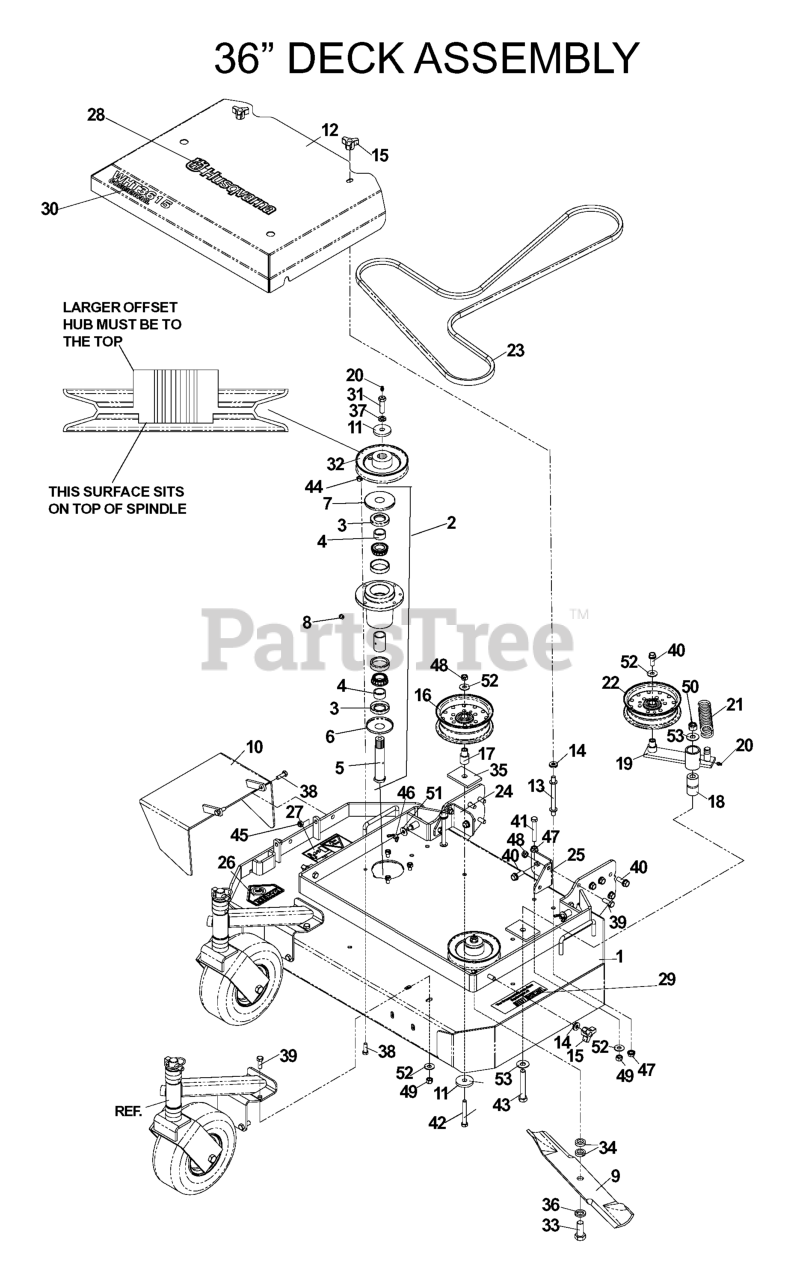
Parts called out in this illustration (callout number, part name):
1	DECK W/DECALS 36"WSL
2	SPINDLE ASM KIT, WHT/KIKW
3	SHAFT SEAL
5	52/61 SPINDLE - SPLINED SHAFT
6	BOTTOM DUST CAP
7	TOP DUST CAP
8	PLUG-VENTED
9	BLADE OEM 18"
10	DEFLECTOR CHUTE
11	SPINDLE WASHER
12	BELT SHIELD, 36" ORANGE
13	SHIELD SPACER
14	WASHER, 3/8 SEALING
15	KNOB, THREE PRONG
16	IDLER PULLEY (TALL)
17	IDLER BUSHING
18	PIVOT BUSHING
20	ZERK
22	IDLER PULLEY
24	DECK SLIDE, RT
25	DECK SLIDE, LT
26	DECAL, CPSC
27	DECAL, EURO SEVERING
28	DECAL, HUSQ 12" BLUE
29	DECAL, NASCAR
30	DECAL, WTH3615
31	HCS 7/16-20 GD 8 SPEC
32	PULLEY - 52"
33	HCS 5/8-18X1-1/2 GR5 TPBLT ZD
34	BLADE SPACERS
36	LOCKWASHER 5/8
37	WASHER 7/16 LOCK
38	HCS 5/16C X 1
39	HCS 3/8-16X1.GRD.5.ZD
40	4CS 3/8C X 1 SERRATED HEAD
41	HCS 3/8C X 2 1/2
42	SCREW 3/8C X 2 3/4 HEX CAP
43	HCS 1/2C X 3 1/4
44	NUT 5/16C CENTERLOCK
45	NUT 5/16 NYLOC
46	WINGNUT, 5/16C NYLOC
47	NUT 3/8C WHIZ
48	NUT 3/8C CENTERBLOCK
49	NUT 3/8-16 NYLOC
50	NUT 1/2-13 HEX NYLOC ZD
51	WASHER 5/16 FLAT
52	WASHER 3/8 FLAT
53	WASHER 1/2 FLAT
